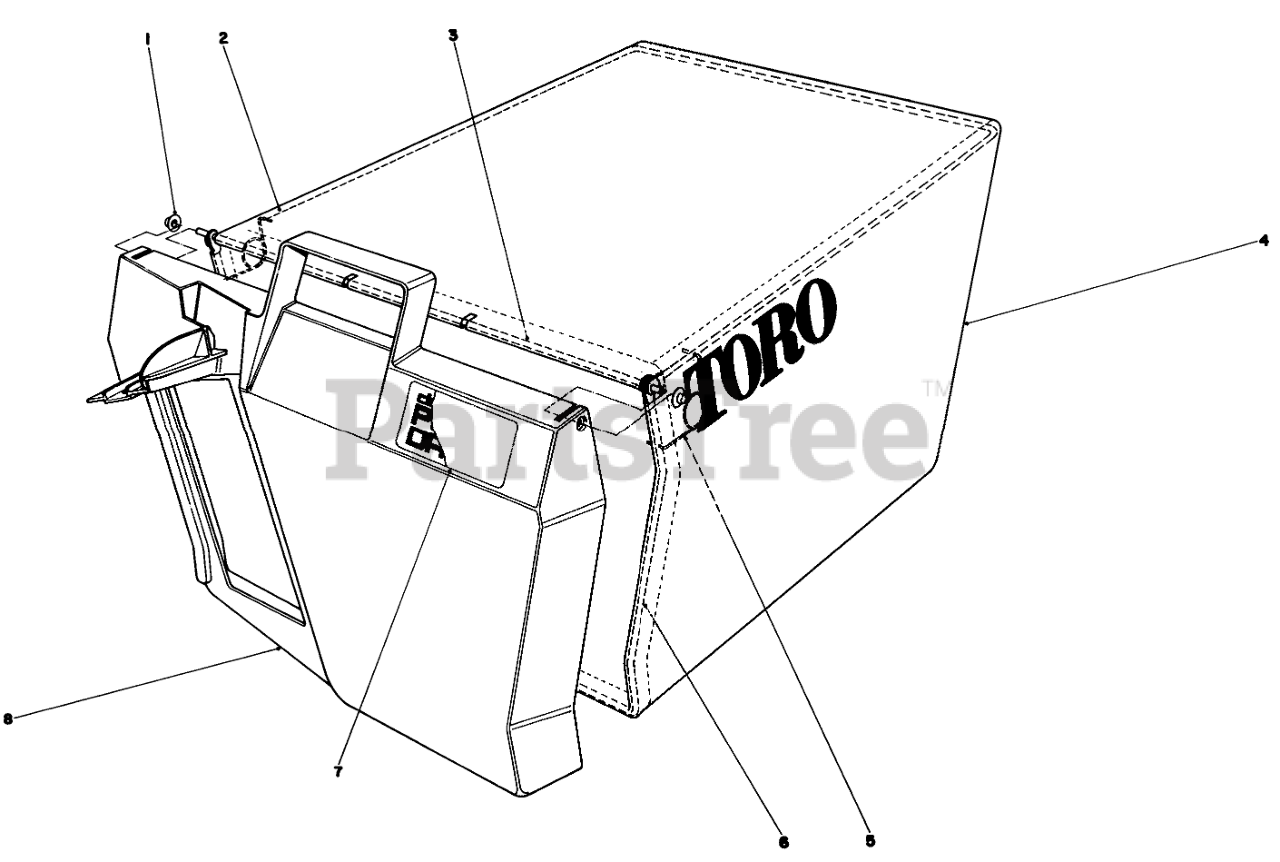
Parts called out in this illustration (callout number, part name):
1	NUT-PUSH
2	Bag Frame Upper
3	HINGE-DOOR, BAG
4	Bag
5	SPRING
6	Frame Bag
7	BAG DOOR DECAL
8	Door Grass Bag
